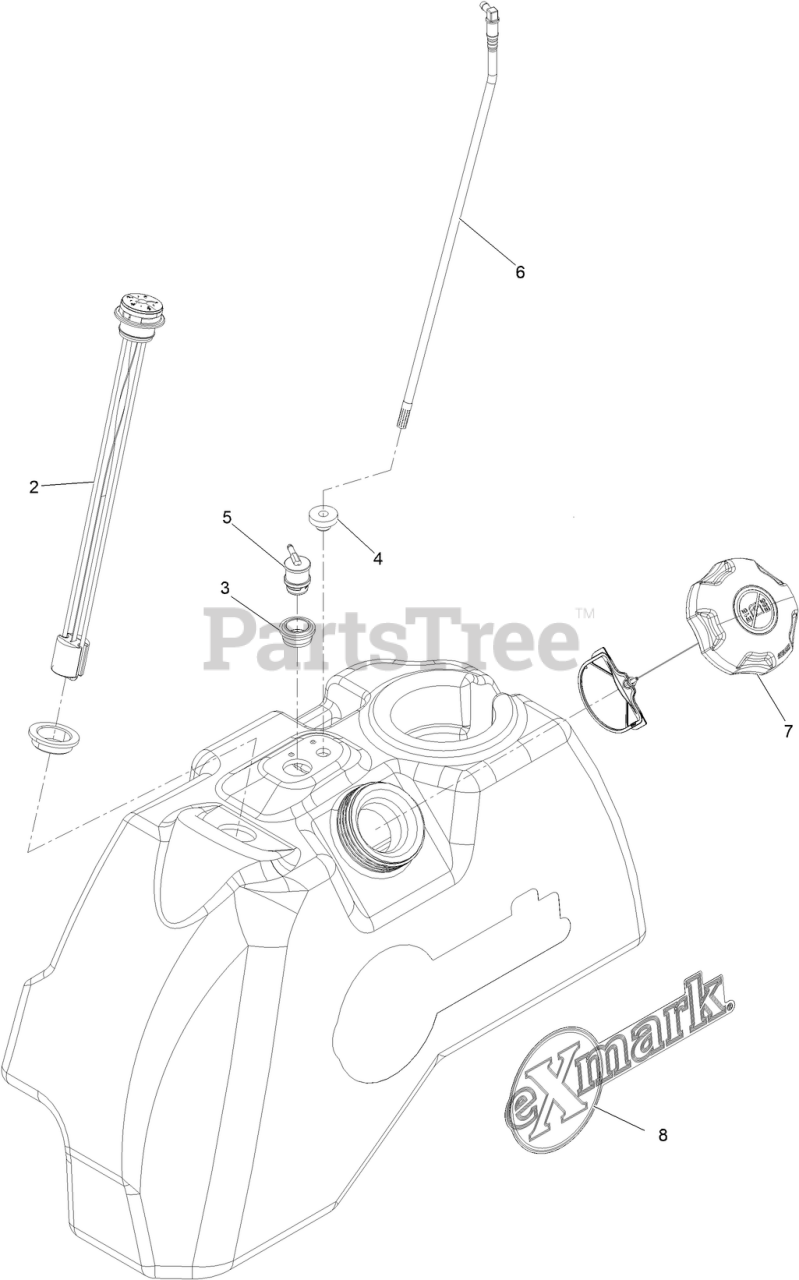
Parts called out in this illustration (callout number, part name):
2	ASM-FUEL GAUGE
3	GROMMET
4	BUSHING
5	VALVE-VENT, FUEL
6	PIPE-STAND
7	CAP-FUEL, RATCHETING
8	DECAL-EXMARK LOGO FUEL
